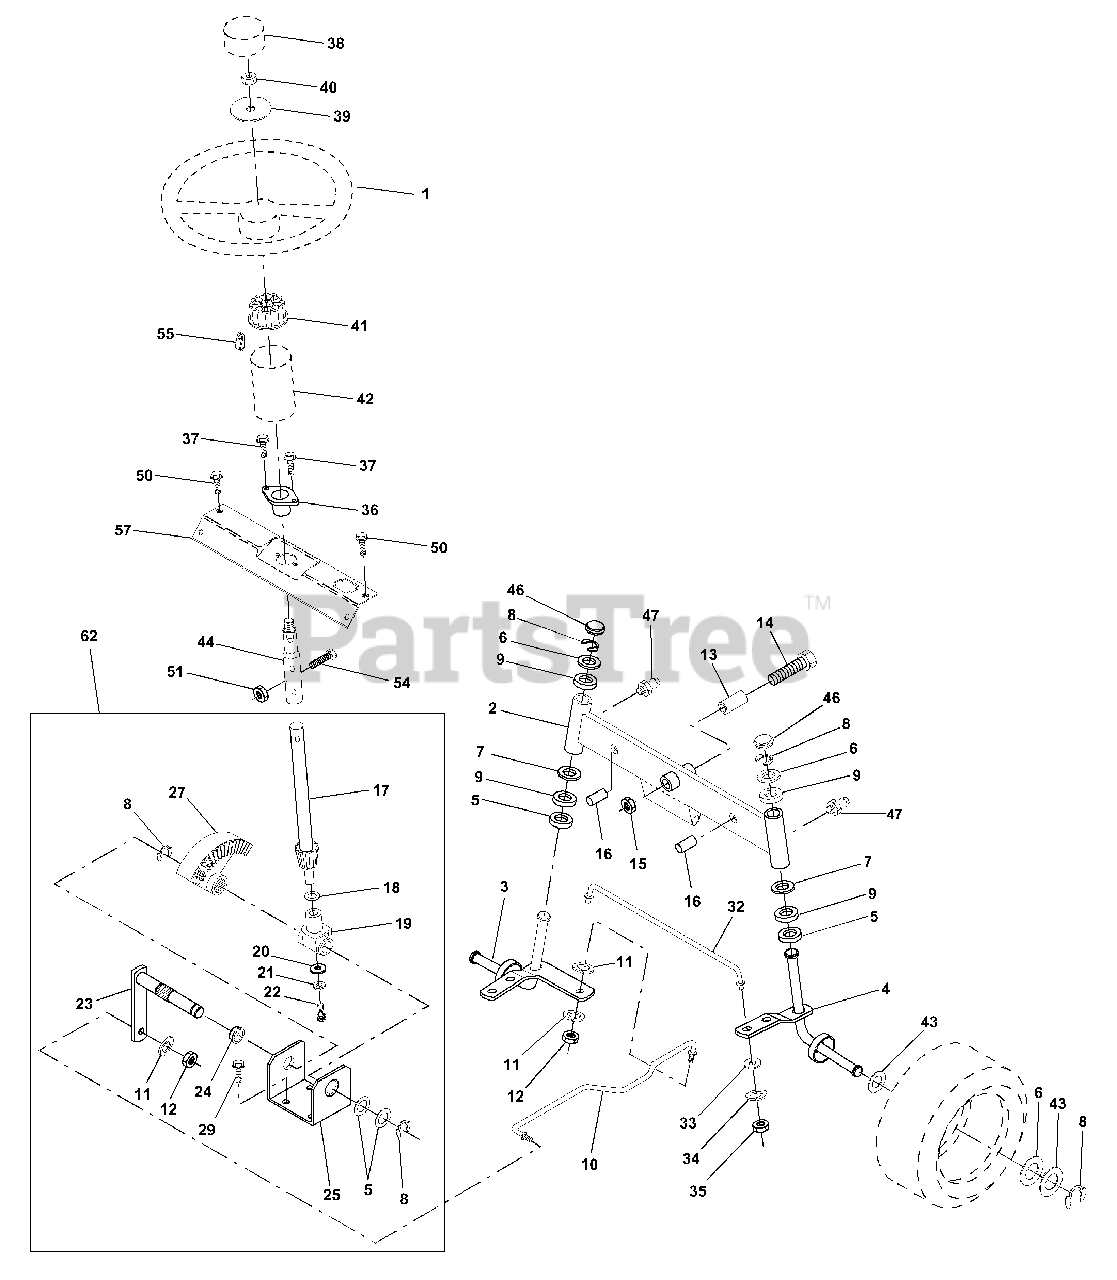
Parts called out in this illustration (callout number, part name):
1	Wheel Steering Auto Grey
2	Axle Asm Fr LT W/gzks 38/42
3	Spindle Asm LH
4	Spindle Asm RH
5	Washer, Thrust .75 x 1.230
6	Washer 25/32 X 1-5/8 X 16 Ga
7	Washer 27/32 X 1-1/4 X 16 Ga
8	Ring Klip #t5304-75
9	Bearing Col Strg Blk
10	Link Drag Sol Ball Jt 20 064
11	Washer Lock Hvy Hlcl Spr 3/8
12	Nut Fin Hex 3/8-24 Unf
13	Spacer Bearing Axle Front
14	Bolt Hex 5/8-11 Unc X 3-1/2
15	Nut Lock Flange 5/8-11 Unc
16	Pin Axle 5/8 X 1 55/1 54 Lg
17	Shaft Asm Strg Private Label
18	Washer Thrust 515 x 750 x 033
19	Support Shaft
20	Washer Shim 1/4 X 5/8 X 062
21	Washer Lock Hvy Helical 1/4
22	Screw Hex Socket 1/4-20 X 5/8
23	Shaft Asm Pittman
24	Nyliner Snap In
25	Bracket Steering
27	Gear Sector
29	Screw Thdrol 3/8-16x3/4 Ty-tt
32	Rod Tie Ball Jt Sol 19.75 Elec.
33	Washer 11/32 x 3/4 x 16 Ga.
34	Washer Lock Hvy HLCL SPR 5/16
35	Locknut 5/16-24 UNF 3847
36	Bushing Strg
37	Screw Slftp #10-16 X 1/2 Ty-b
38	Insert Cap Strg Wh Au Husq Gry
39	Washer 13/32 X 2-3/8 X 8 Ga
40	Nut Lock Center 3/8-24unf
41	Adaptor Wheel Strg 640/ 635id
42	Boot Steering Shaft
43	Washer 25/32 X 1 1/4 X 16 Ga
44	Shaft Extention Steering
46	Cap Spindle Fr Top Blk
47	Fitting Grease
50	Screw Hex Wsh Thdrol 1/4-20 x 3/4
51	Nut Lock Hex w/Ins 5/16-18
54	Bolt Fin Hex 5/16-18 Unc x 1-1/4
55	Clip Tinnerman
57	Support Shaft Steering
62	Kit, Steering Assembly
